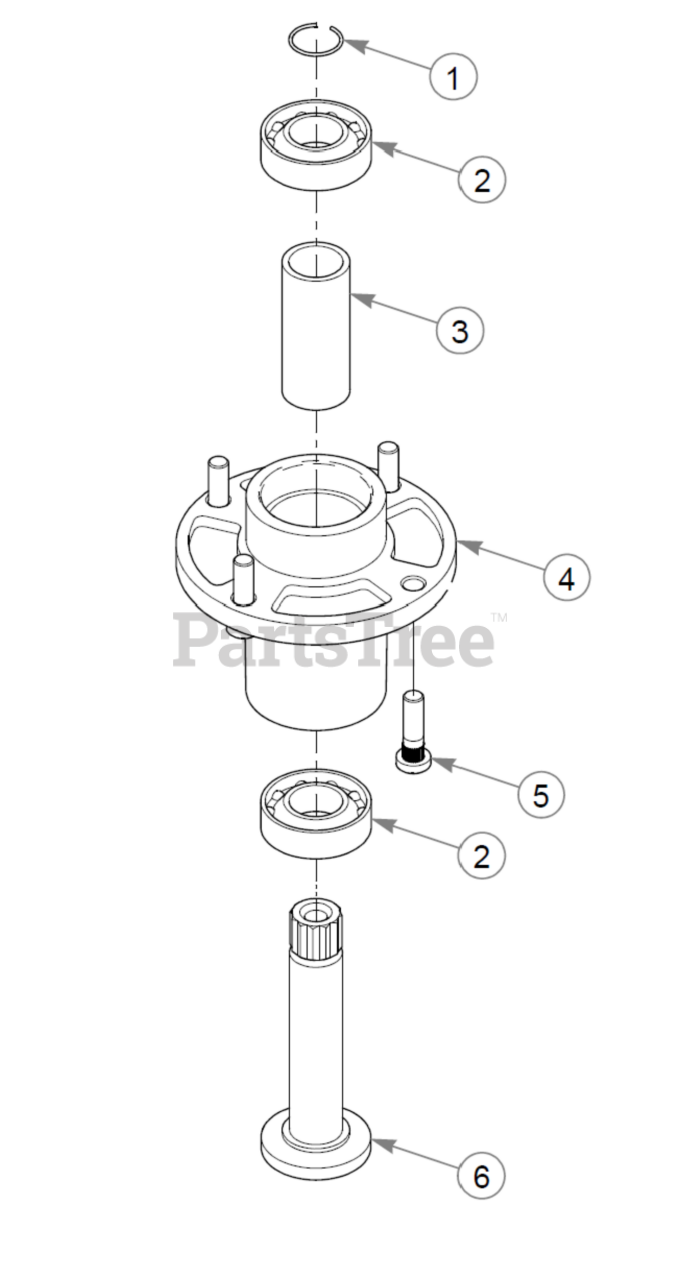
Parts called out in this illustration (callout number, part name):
1	RING, BLADE SPINDLE RET
2	BEARING, 6205 2RST C3
3	SPACER, BLADE SPINDLE
4	SVC, SPINDLE HOUSING
5	AXEL BOLT 3/8-16 X 1.375
6	SHAFT, BLADE SPINDLE
